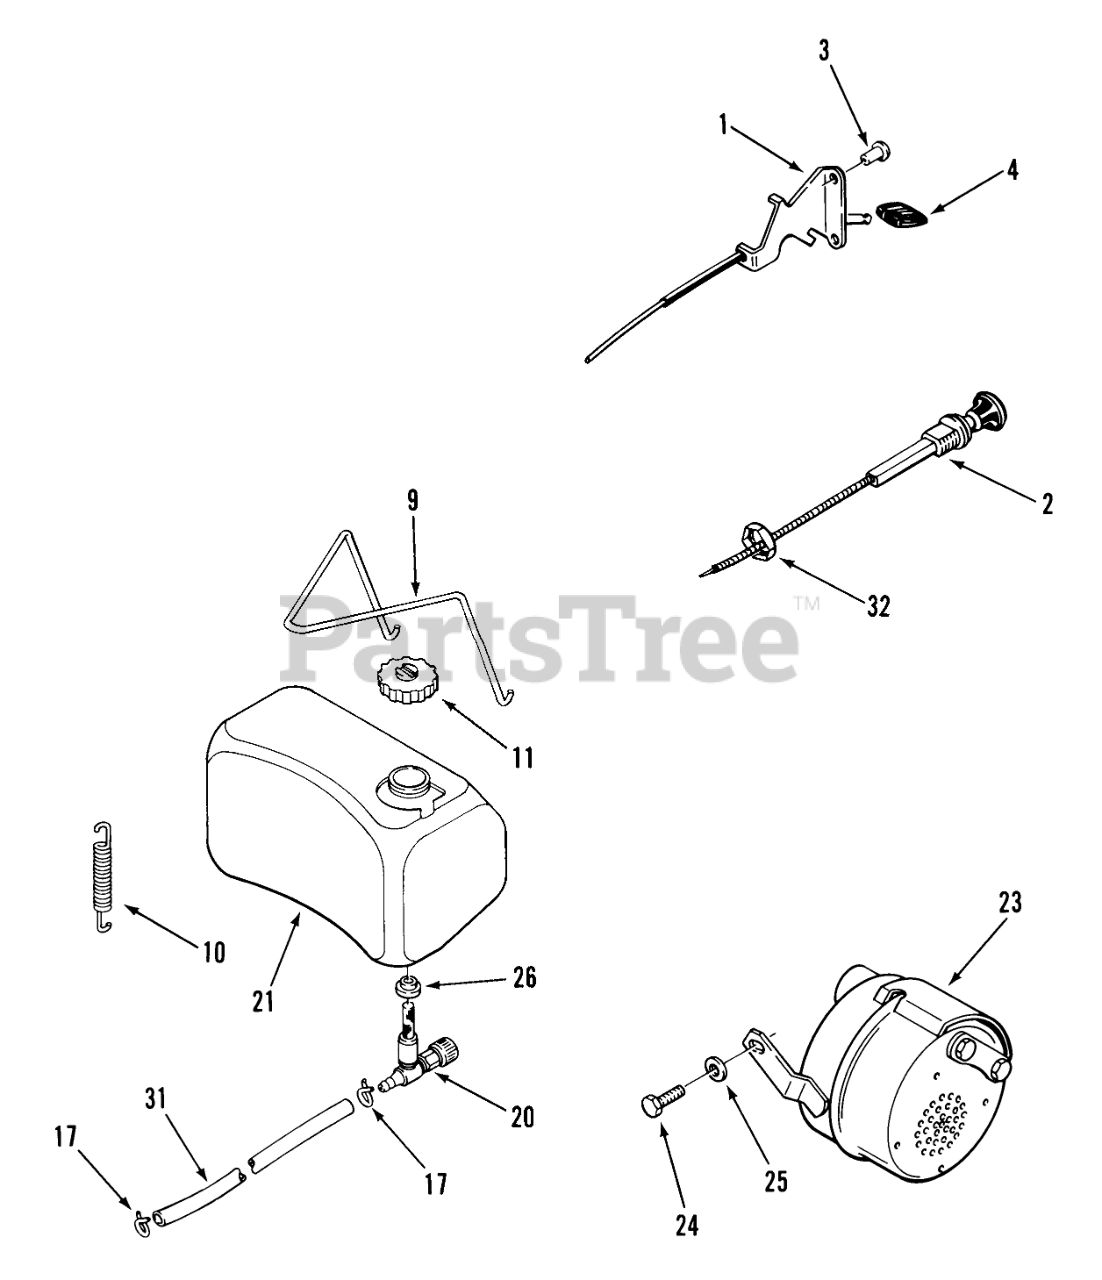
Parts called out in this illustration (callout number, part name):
1	CONTROL- THROTTLE
1	Choke/Throttle Control LT-1100 Only
2	CONTROL-CHOKE
3	RIVET-4
4	KNOB-THROTTLE
9	Hold Down Wire
10	SPRING-EXTENSION
11	Gasoline Cap
11	CAP-GASOLINE
17	Clamp
20	VALVE-FUEL
21	Fuel Tank Assy
23	ASSY-MUFFLER
24	Bolt
26	BUSHING
31	Fuel Hose 18"
31	Hose
32	NUT-HEX PALNUT
